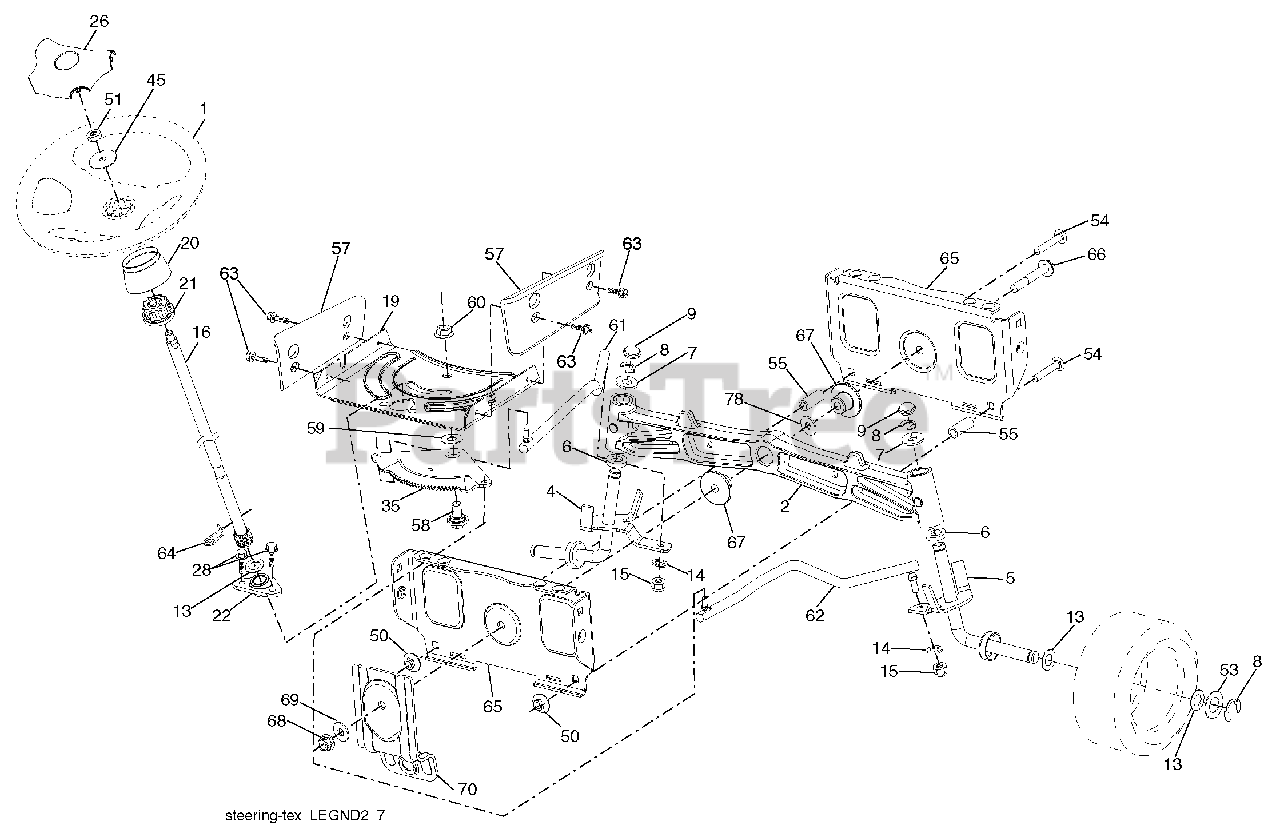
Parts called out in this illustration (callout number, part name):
1	Wheel, Steering
2	Axle Asm., Front
4	Spindle Asm., LH
5	Spindle Asm., RH
6	Bearing, Race Thrust Harden
7	Washer 25/32 x 1-5/8 x 16 Ga.
8	Ring, Clip #T5304-75
9	Cap, Spindle
13	Washer 25/32 x 1-1/4 x 16 Ga.
14	Washer, Lock Hvy Hlcl Spr 3/8
15	Nut, Crown Lock 3/8-24 unf
16	Shaft Steering
19	Plate Steering
20	Boot, Steering
21	Adapter, Wheel Steering
22	Bushing, Strg. Blk
26	Insert, Wheel Steering
28	Screw 3/8-16 x 3/4
35	Gear, Sector Plate
45	Washer 9/16 ID x 2-3/8 x 12 Ga.
50	Nut Lock 3/8-16 unc
51	Nut Hex Jam Toplock 1/2-20 unf
53	Washer Hardened .793 x 1.637 x .060
54	Bolt Hex 3/8-16 unc x 2-1/4
55	Spacer Brace Axle
57	Bracket Upstop
58	Bolt Shoulder Sector Pivot CFM
59	Washer Thrust Sector Steering
60	Nut Flange Lock 5/8-11
61	Draglink, LH
62	Draglink, RH
63	Screw 5/16-18 x 3/4
64	Retainer Clip Spring Steering
65	Brace Axle Front
66	Bolt Hex Fghd 7/16-14 x 3 Serr
67	Bushing PM Front Axle
68	Nut Lock Flange 7/16-14 Gr. 5
69	Washer 1.5 x .505 x .118
70	Bracket Deck Susp. Front
78	Washer Thrust .515 x .750 x .033
